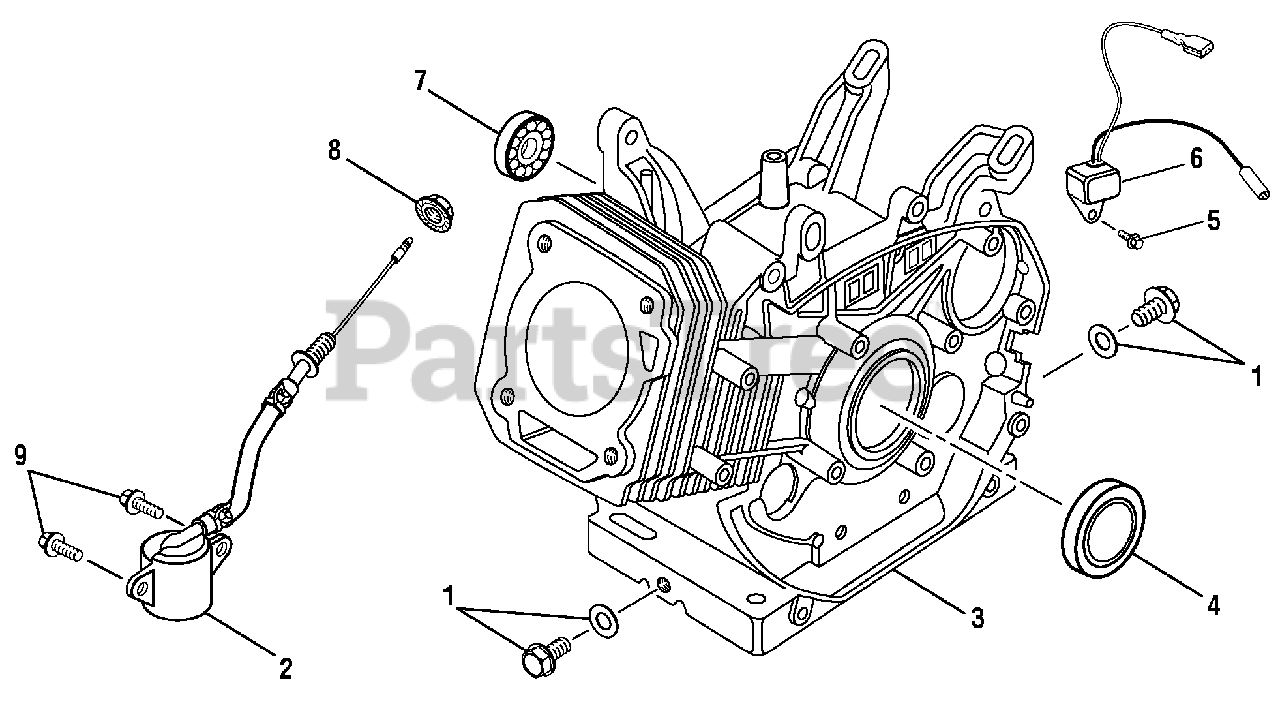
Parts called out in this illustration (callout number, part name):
1	Drain Plug Assembly
2	Oil Sensor Assembly
3	Short Block Cover Assembly w/Crankcase
4	Oil Seal (35 mm x 52 mm x 8 mm)
5	Bolt (M6 x 12 mm Flange Hd.)
7	Ball Bearing (6202)
8	Flange Nut (M10)
9	Bolt (M6 x 16 mm, Flange Hd.)
